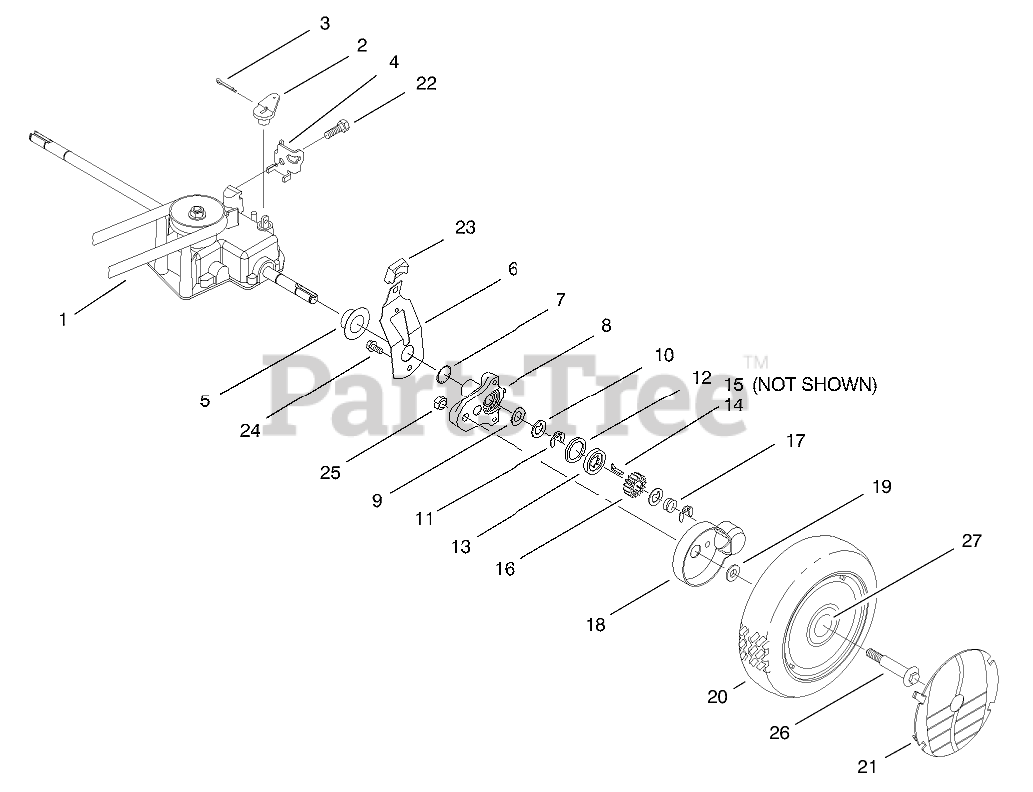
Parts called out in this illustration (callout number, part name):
1	V-BELT E
2	LEVER-SHIFT
3	PIN-COTTER
4	CLAMP-CABLE
5	CAP-END
6	SPRING ARM ASM
7	O-RING
8	ASM
9	WASHER-ARM, PIVOT
10	WASHER-THRUST, KEYED
11	RING-CLIP, LOCKING
12	RING-FRICTION
13	WASHER-CLUTCH
14	KEY-ROCKING, LH
15	KEY-ROCKING, RH
16	GEAR-PINION
17	SPRING-COMPRESSION
18	COVER-WHEEL
19	SPACER-COVER, WHEEL
20	WHEEL AND TIRE ASM (W/GEAR)
21	WHEEL COVER
22	SCREW-HWHTF
23	KNOB-ARM
24	SCREW-HWH
25	NUT-LOCK
26	BOLT-WHEEL
27	BUSHING
